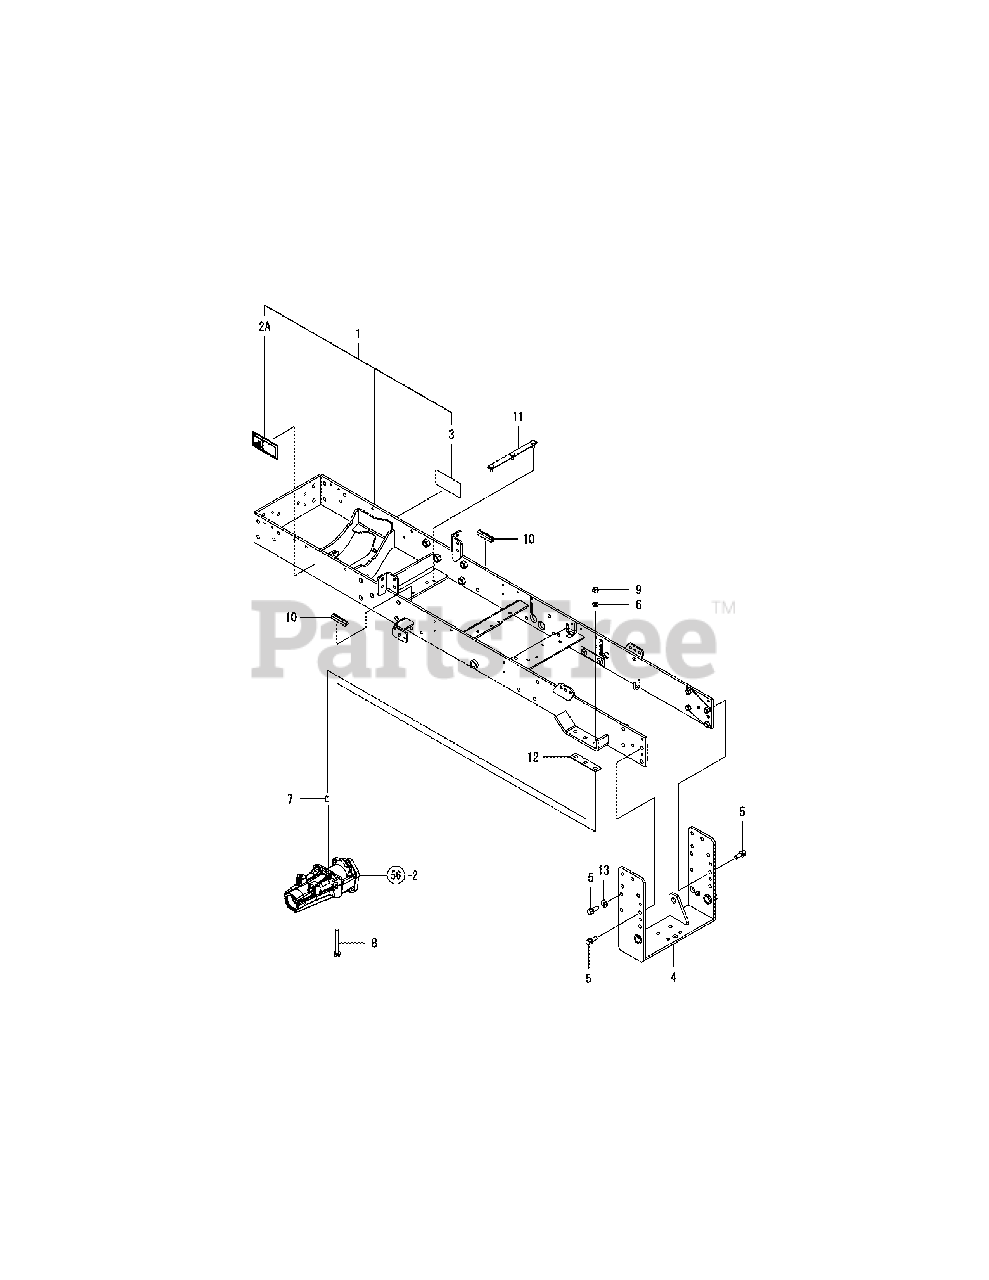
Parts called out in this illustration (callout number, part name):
1	Sct Frame M Assy
2A	Label, Warnibg, Stop
3	Label, Danger, Start
4	Frame, Lower Cmp
7	Pin, 10.0A X 20
8	Bolt, 12 X 100
11	Plate, Fuel Tank Cover
12	Shim, 1.2
13	Washer 12, Polished
